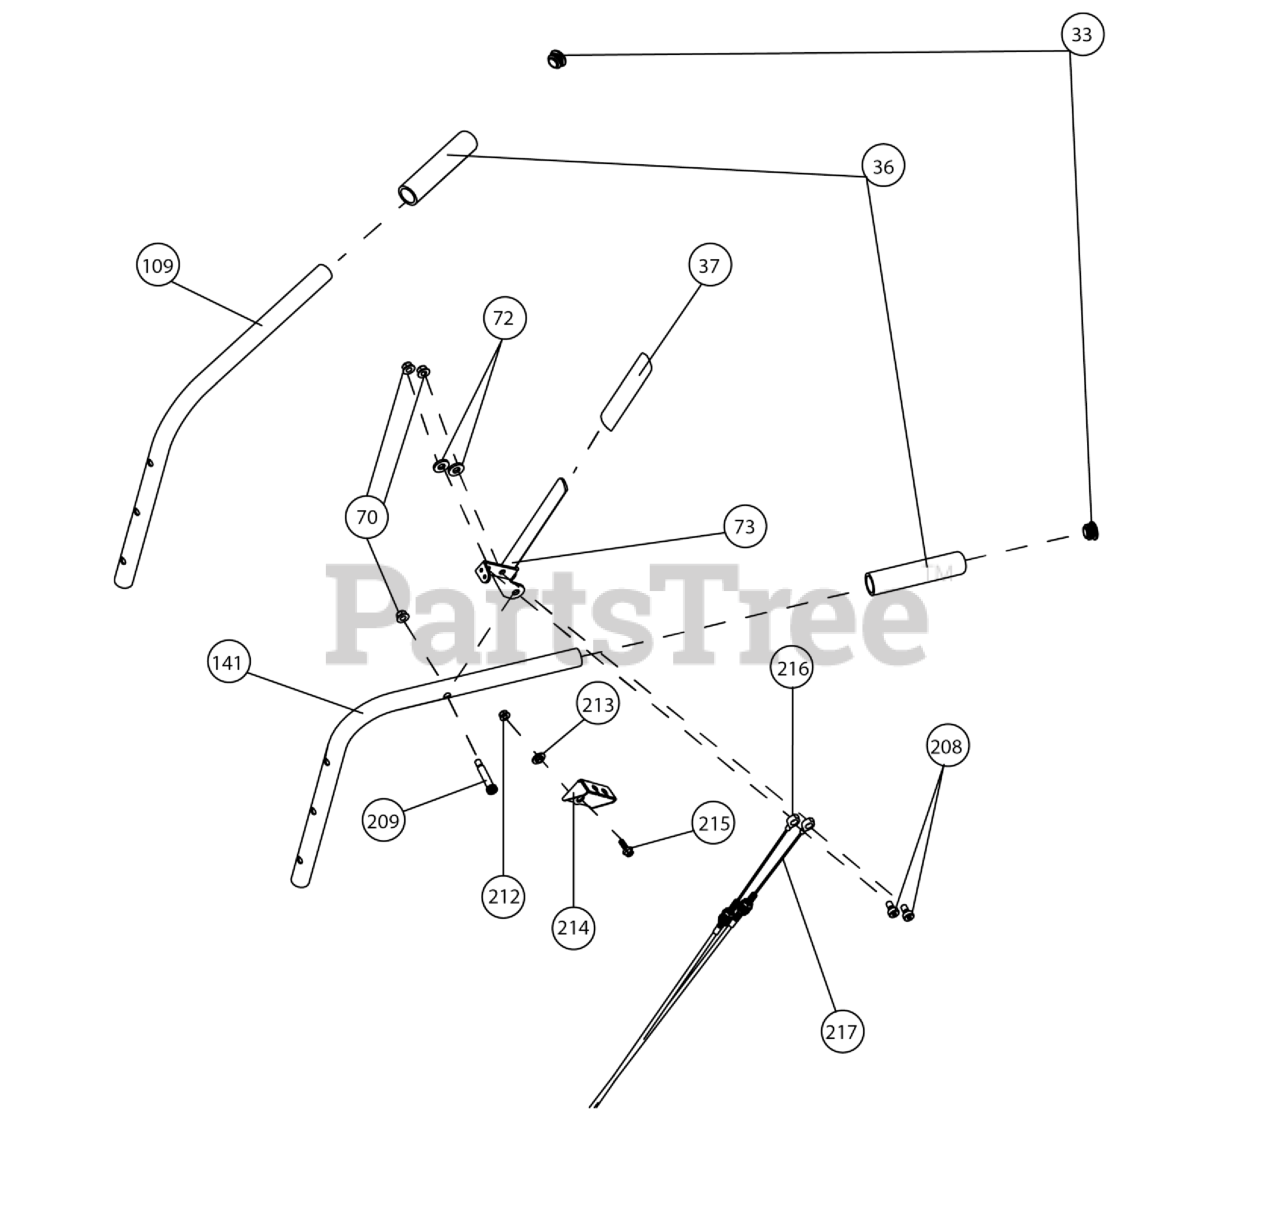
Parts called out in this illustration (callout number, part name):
33	PLUG TUBE INSERT 1" OD
36	GRIP HANDLE
37	GRIP LEVER 0.125" X 1" X 5" ORANGE
70	NUT-HEX-NYLK, FLG .3125-18 ZP
72	WSHR-STL, FLT, .406" X .875" X .125" ZP
73	SEE: 351624
109	SEE: 351618
141	SEE: 351619
208	BLT-SLDR,SH.375"X.50",.313"-18X.50"G8ZP
209	BOLT SHOULDER 3/8 X 1 1/2"
212	NUT-HEX-NYLK, FLG .250"-20 ZP
213	WASHER, SHOULDER .265"X.437"X.125" NYL
214	BRKT, CABLE MOUNT
215	SCR-MAC, HWH .250"-20 X .750" G2 ZP
216	CABLE, REEL OSSP
217	CABLE, SEED DROP, OSSP
